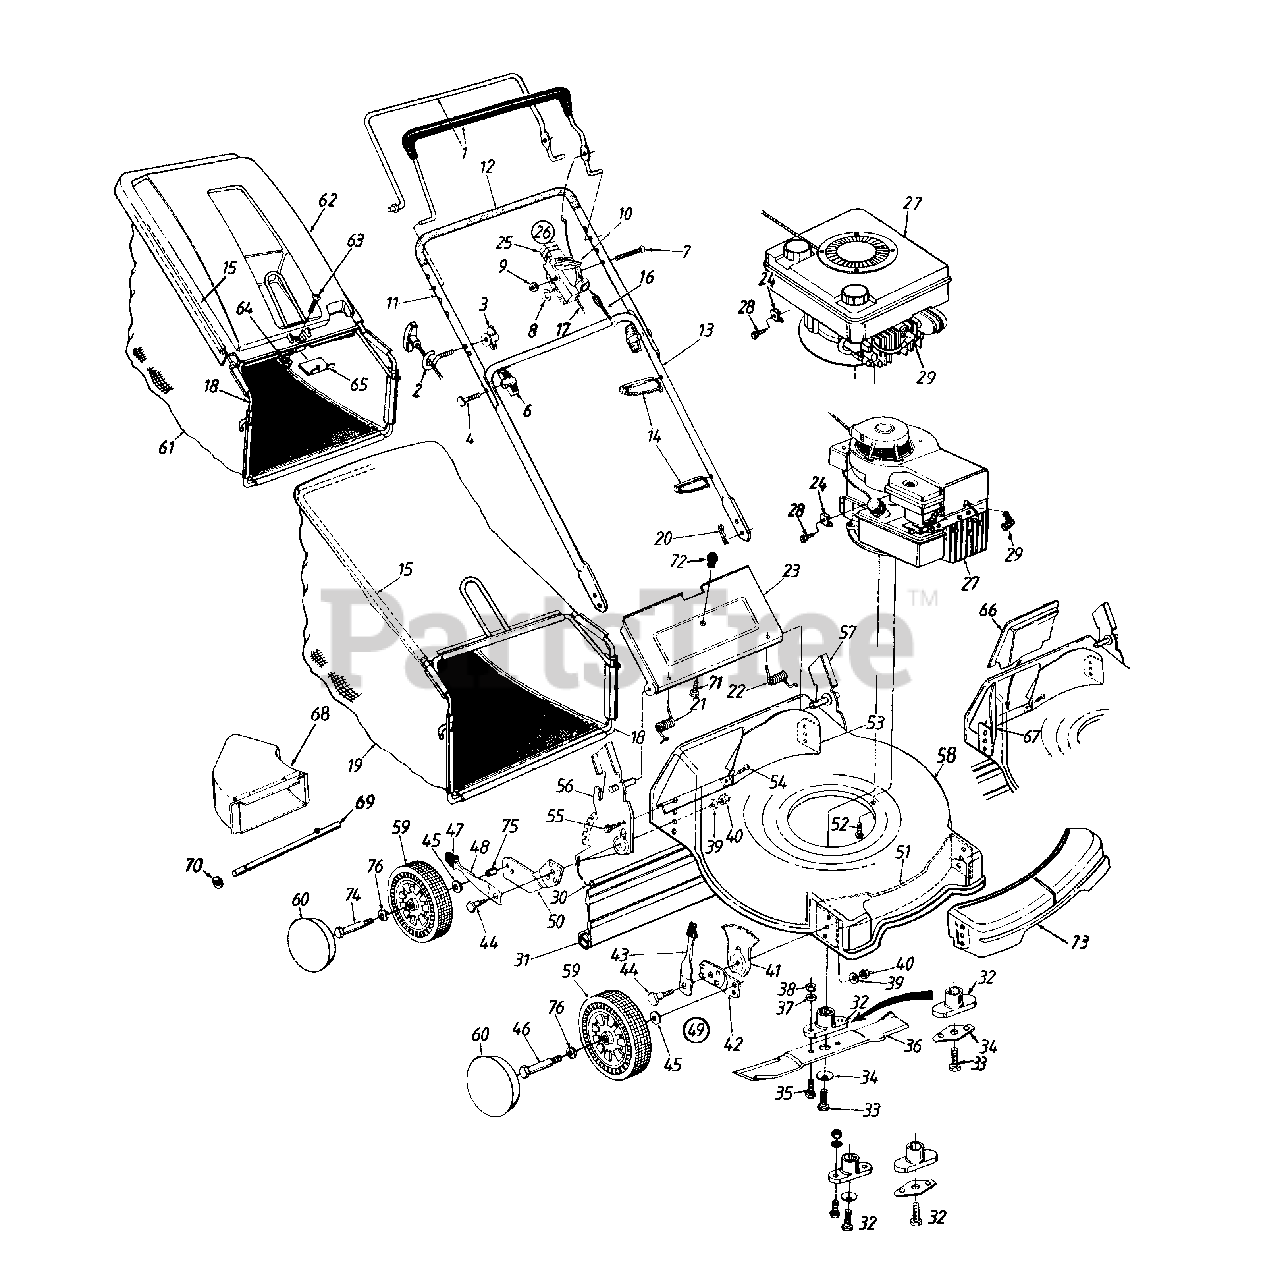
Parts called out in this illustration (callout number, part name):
2	Rope Guide
3	Handle Knob 1/4 - 20 Thd.
4	Curved Hd. Bolt 5/16-18 x 2" Lg
6	Hand Knob
7	Oval C-Sunk Mach. Scr.
8	Spr. Wash. .66" I.D.
9	Hex L-Nut 1/4-20 Thd.
10	Throttle Lever
14	Cable Tie
16	Control Cable-39"
17	Throttle Control Wire - 51"
20	Int. Cotter Pin 5/16" Dia.
21	Door Spring - R.H.
22	Door Spring - L.H.
25	Throttle Body
26	Throttle Box Comp.
27	Engine
28	Hex Wash. Hd. Scr. #10-32 x .62" Lg. (B & S)
29	Spark Plug Boot
30	Wire Rod
31	Rear Flap
32	Blade Adapter Kit
33	Hex Bolt 3/8-24 x 1.5" Lg.
34	Bell-Wash. .39" I.D.
35	Hex Bolt 3/8-24 x 1" Lg.
36	21" Blade - 3 Bolt Mount
37	L-Wash. 3/8" I.D.
38	Hex Nut 3/8-24 Thd.
39	Bell-Wash. .39" I.D. x 1.38"
40	Hex Nut 3/8-16 Thd.
41	Height Adj. Plate
43	Spring Lever Ass'y. w/Knob
44	Shld. Bolt .5" Dia. x .357"
45	Bell-Wash. .38" I.D. x .88" O.D.
46	Axle Bolt
47	Spring Lever Knob
48	Spring Lever
49	Height Adj. Ass'y. Comp. - R.H.
50	Pivot Bar R.H.
54	Torx Mach. AB-Tap Scr. 1/4 x 62" Lg.
55	Hex Ind-Wash.Scr. 1/4 -14 x .625 Lg.
61	Grass Bag
62	Hard Top Cover
63	Pan Hd. Mach. Scr. 1/4-20 x .5" Lg.
64	Hex Nylon L-Nut 1/4-20 Thd.
68	Deflector
69	Rod
70	Push Speed Nut
71	Truss Scr. #10-24 x .38" Lg.
73	Deck Shroud
74	Rear Axle Bolt
75	Spacer
76	Wave Washer
